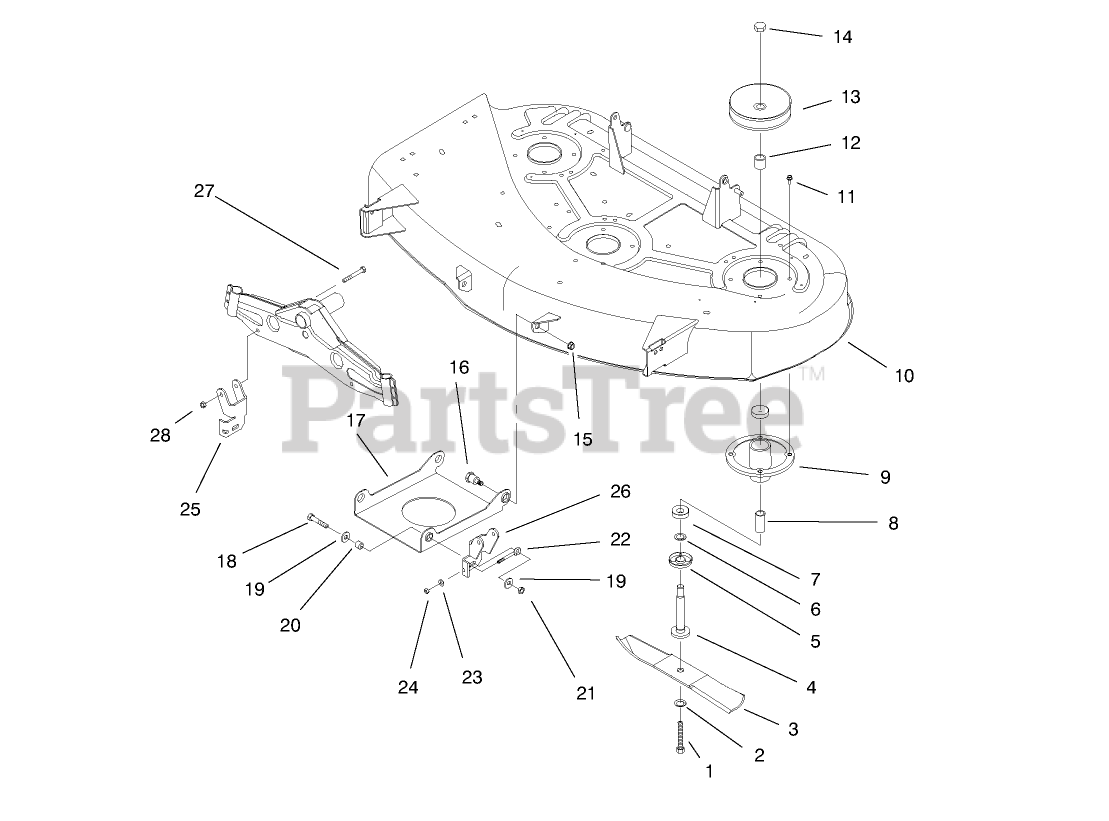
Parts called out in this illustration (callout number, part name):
1	SCREW-HH
2	WASHER-BELLEVILLE
4	SHAFT-SPINDLE
5	SHIELD-BEARING
6	SPACER
7	BEARING-BALL
8	SPACER
9	HOUSING-SPINDLE
11	SCREW-TAPTITE
12	SPACER
13	PULLEY
14	NUT-HEX
15	NUT-LOCK, NI
17	PAN-DECK SUSPENSION, FRONT
18	SCREW-HH
19	WASHER-HARDENED
20	SPACER
21	NUT-LOCK, NI
22	SCREW-ADJUSTING
23	WASHER-FLAT
24	NUT-LOCK, NI
25	BRACKET-DECK, RH
26	BRACKET-DECK, LH
27	SCREW-HH
28	NUT-LOCK, NI
